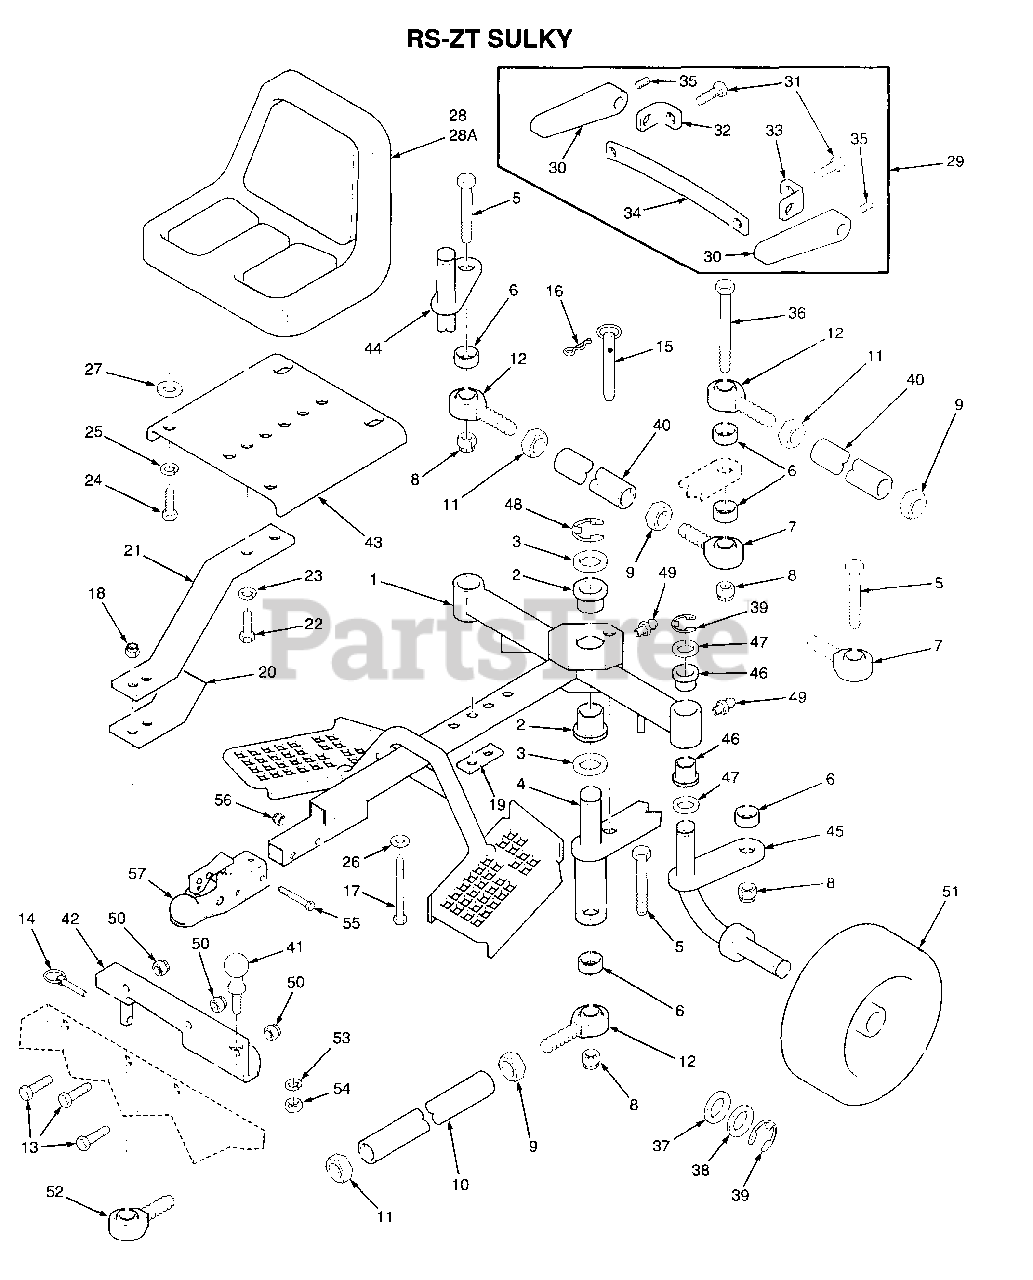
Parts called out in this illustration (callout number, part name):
1	Sulky Frame
2	Bronze Bearing
3	Flat Washer
4	Steering Bellcrank
5	Hex Head Bolt, 1/2-13 x 2"
6	Ball Joint Spacer
7	Ball Joint (RH Thread), 1/2-20
8	Elastic Stop Nut, 1/2-13
9	Hex Nut, 1/2-20
10	Tie Rod, Long
11	Hex Nut (L.H. Thread), 1/2-20
12	Ball Joint (L.H. Thread), 1/2-20
13	Hex Head Bolt, 3/8-16 x 1-1/4"
14	Quick Pin, 3/16" dia
15	Ring Pin
16	Hair Pin, .094 x 1.625
17	Hex Head Bolt, 7/16-14 x 4"
18	Elastic Stop Nut, 7/16-14
19	Lower Support Plate
20	Reinforcement Seat Spring
21	Seat Support Spring
22	Hex Head Bolt, 3/8-16 x 1"
23	Lock Washer, 3/8"
24	Hex Head Bolt, 5/16-18 x 3/4"
25	Lock Washer 5/16"
26	Flat Washer, 7/16"
27	Flat Washer, 3/8"
28	Seat Assembly
28A	Seat
29	Arm Rest Kit
30	Arm Rest
31	Hex Head Bolt, 5/16-18 x 3/4"
32	Mounting Bracket, RH
33	Mounting Bracket, LH
34	Back Strap
35	Set Screw, 3/8-16 x 3/4" Flat Point
36	Hex Head Bolt, 1/2-13 x 3-1/4"
37	Flat Washer, 1"
38	Flat Washer, 1"
39	"E" Clip, 1"
40	Tie Rod
41	Hitch Ball, 1-7/8"
42	Hitch Bracket
43	Seat Plate
44	Wheel Spindle, RH
45	Wheel Spindle, LH
46	Bronze Bearing
47	Flat Washer
48	"E" Clip
49	Grease Fitting
50	Elastic Stop Nut, 3/8-16
51	Wheel Assembly
52	Ball Joint (RH Thread) 5/8 x 1/2-20
53	Lockwasher, 3/4"
54	Hex Nut, 3/4-16
55	Hex Head Bolt, 3/8-16 x 2-3/4"
56	Elastic Stop Nut, 3/8-16
57	Coupler, 1-7/8"
